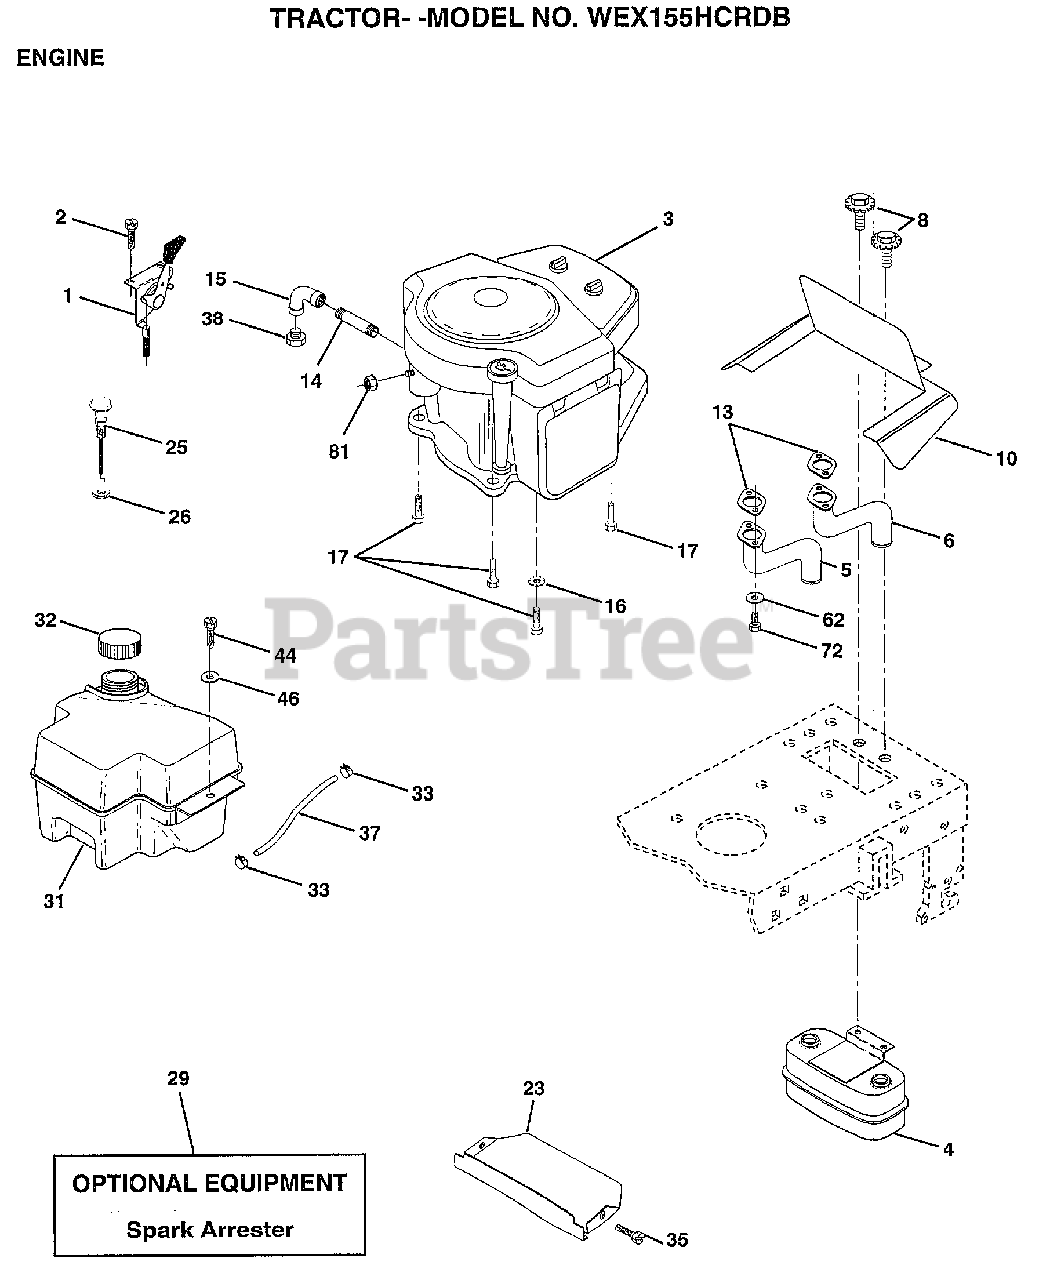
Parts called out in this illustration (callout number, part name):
1	CONTROL THROT. LH
2	SCREW LT
4	MUFFLER.TW.LOTONE
5	TUBE MANIFOLD LH
6	TUBE MANIFOLD RH
8	BOLT.5/16-18.UNC
10	SHIELD.BROWNING
14	PIPE NIPPLE LT
15	ELBOW
16	LOCKWASHER
17	SCREW LT
23	SHIELD.BRN/DBR.GD
25	CONTROL.CHOKE.37
26	"NUT,KEPS 3/8-24IM"
31	TANK.FUEL.FRONT.
32	CAP ASM FUEL
33	HOSE CLAMP
35	SCREW
37	LINE FUEL
44	SCREW HEX CRT
46	WASHER
62	LOCKWASHER
72	SCREW
81	NUT
